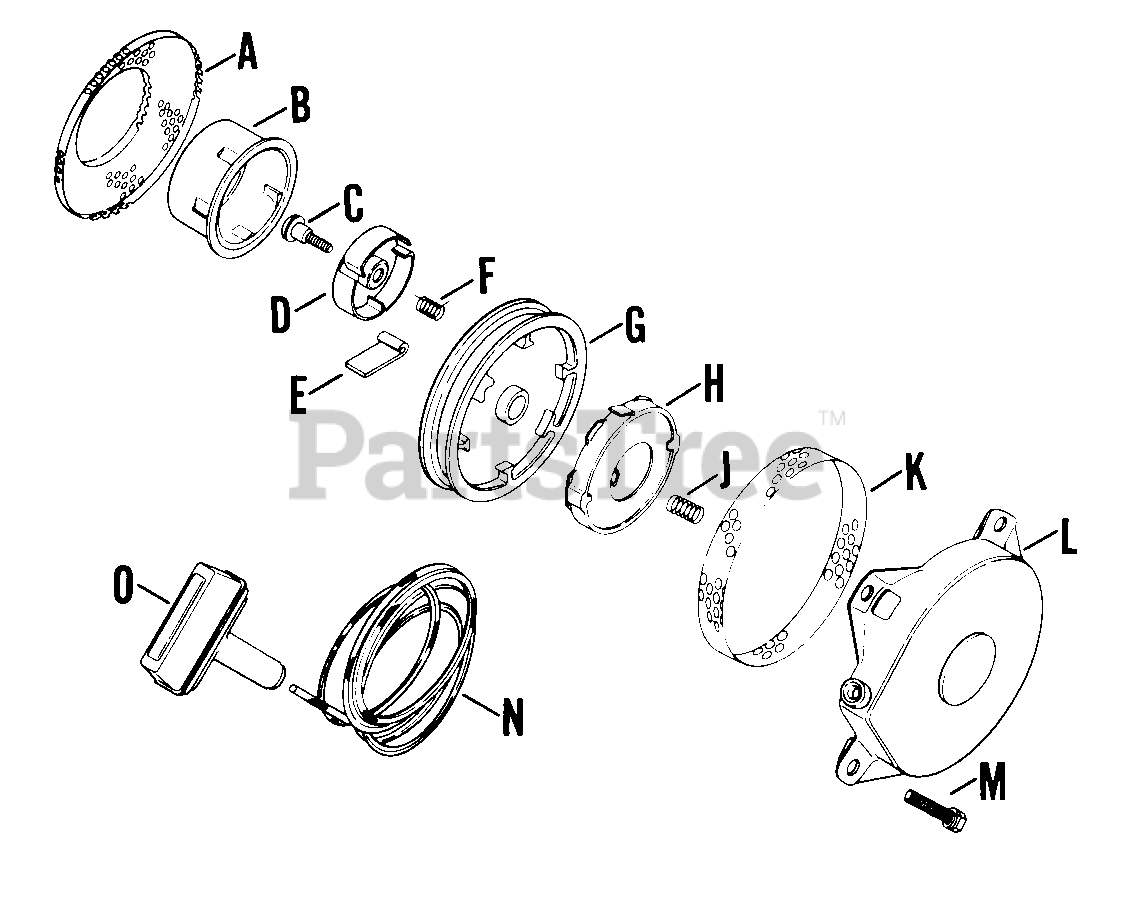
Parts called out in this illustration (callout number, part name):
4616501	STARTER - USE 46 755 02
B	HUB
C	SCREW - DISCONTINUED
E	DOGS - DISCONTINUED
F	SPRING - DISCONTINUED
H	SPRING - (#DSC)
J	SPRING - DISCONTINUED
K	SCREEN - DISCONTINUED
L	HOUSING - DISCONTINUED
N	ROPE - DISCONTINUED
O	HANDLE - USE 25 166 01
